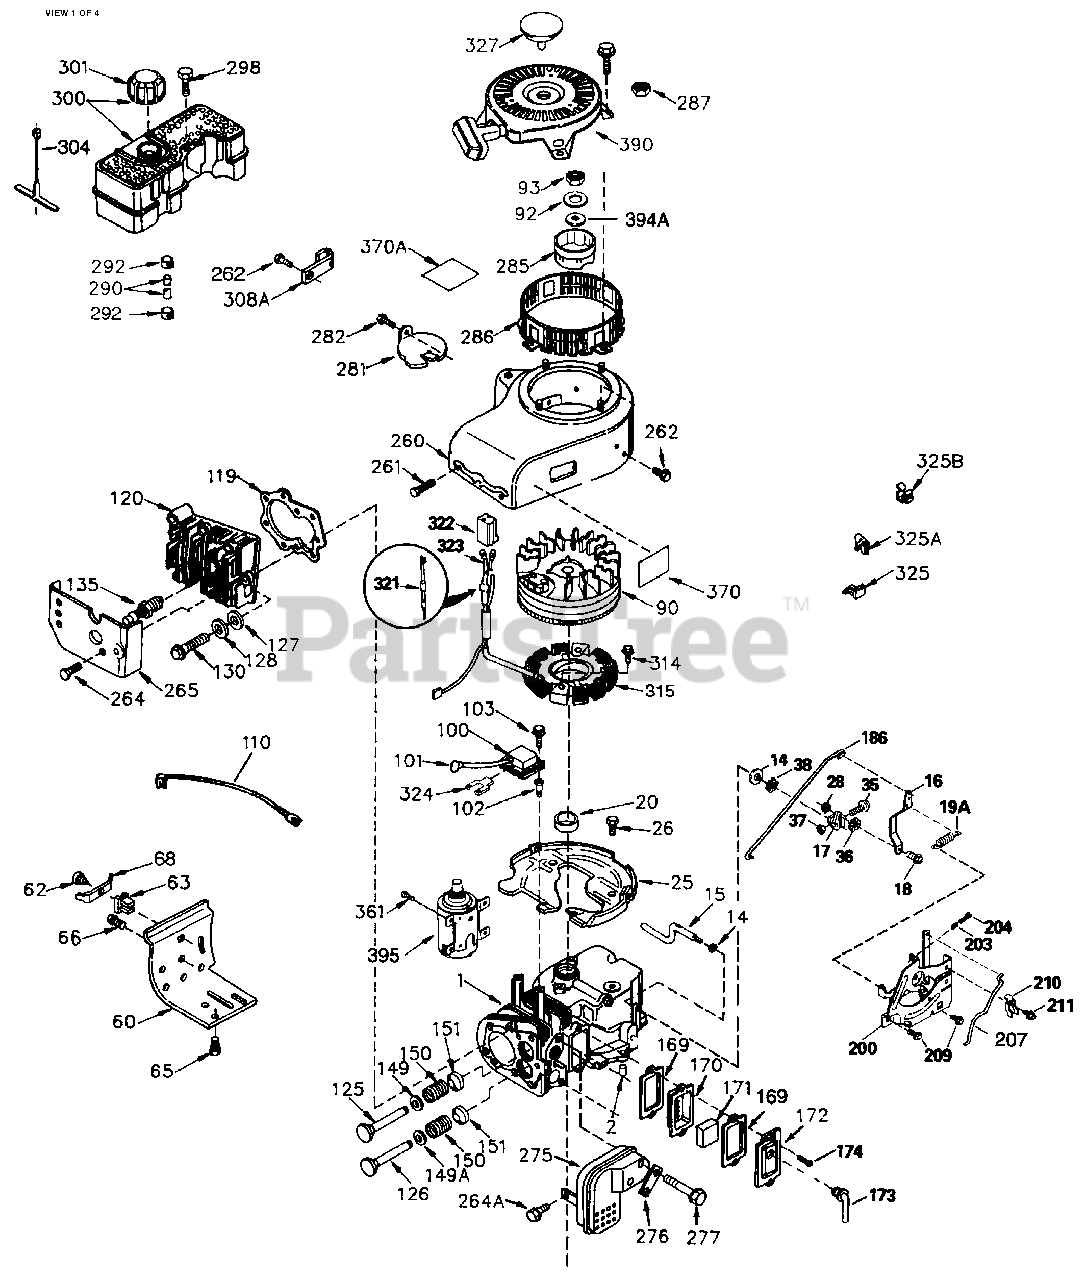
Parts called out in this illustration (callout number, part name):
1	"Cylinder (Incl. 2 & 20)
2	Dowel Pin
14	Flat Washer
15	Governor Rod
16	Governor Lever
17	Governor Lever Clamp
18	Screw, Torx T-15, 8-32 x 3/8"
19A	Extension Spring
20	Oil Seal
25	Blower Housing Baffle (Incl. 325)
26	Screw, 1/4-20 x 5/8"
28	Lock Nut, 8-32
35	Screw, 10-32 x 3/4"
36	Lock Washer #8
37	Lock Nut, 10-32
38	Retaining Ring
60	Blower Housing Extension
65	Screw, 10-24 x 1/2"
66	Screw, Torx T-30, 1/4-20 x 15/32"
90	Flywheel
92	Lock Washer
93	Flywheel Nut
100	Solid State Ignition
101	Spark Plug Cover
102	Solid State Mounting Stud
103	Screw, Torx T-15, 10-24 x 15/16"
110	Ground Wire
119	* Cylinder Head Gasket
120	Cylinder Head
125	Exhaust Valve (Std.)(Incl. 151)
125	Exhaust Valve (1/32" OS) (Incl. 151)
126	Intake Valve (Std.) (Incl. 151)
126	Intake Valve (1/32" OS) (Incl. 151)
128	Belleville Washer
130	Screw, 5/16-18 x 2"
135	Resistor Spark Plug - RJ17LM
149	Valve Spring Cap
149A	Valve Spring Cap
150	Valve Spring
151	Valve Spring Keeper
169	* Valve Cover Gasket
170	Breather Body
171	Breather Element
172	Valve Cover
173	Breather Tube
174	Screw, 10-24 x 1/2"
186	Governor Link
200	Control Bracket (Incl. 203 & 204)
203	Compression Spring
204	Screw, Torx T-10, 5-40 x 7/16"
207	Governor Spring Link
209	Screw, 10-24 x 9/16"
260	Blower Housing
261	Screw, 5/16-18 x 3/4"
262	Screw, T-40, 5/16-24 x 21/32"
264A	Screw, 1/4-20 x 5/8"
265	Cylinder Head Cover
275	Muffler
276	Locking Plate
277	Screw, 5/16-18 x 3-3/16"
281	Starter Bubble Cover
282	Screw, 8-32 x 3/8"
285	Starter Cup
287	Nut & Lock Washer 1/4-28
290	Fuel Line
292	Fuel Line Clamp
298	Screw, 10-32 x 35/64"
300	Fuel Tank (Incl. 292, 298 & 301)
301	Fuel Cap
325	Wire Clip
327	Starter Plug
370	Identification Decal Not for use with 2-cycle engines.
370B	Throttle Decal
390	Rewind Starter Note: This engine cou ld have been built with 590746 starte r.
